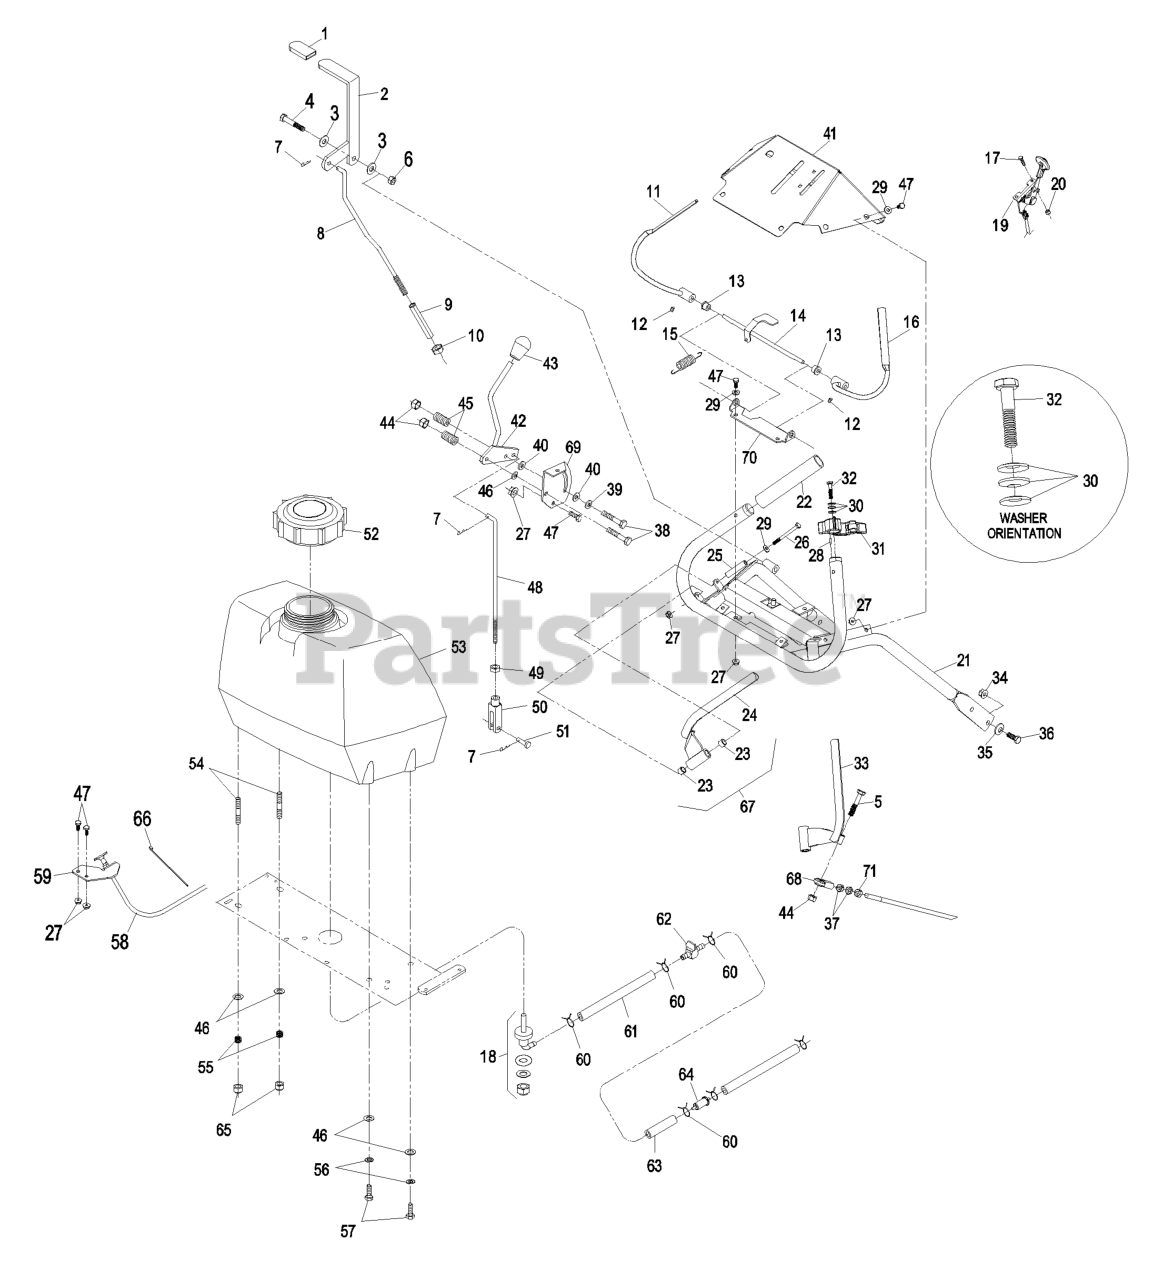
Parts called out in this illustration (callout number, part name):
1	GRIP-LEVER
3	WASHER-FLAT
4	SCREW-HH
5	SCREW-HH
6	NUT-LOCK, NI
7	PIN-COTTER
8	LINK,BLADE ENGAGE (PLTD)
9	TURNBUCKLE
10	NUT-HEX
12	SCREW-SET
13	BUSHING-NYLON
14	WLD,OPC LEVER AXLE
15	SPRING-EXTENSION
17	BOLT-CARR
18	FITTING-FUEL, BULKHEAD
19	CONTROL-THROTTLE
20	NUT-LOCK, NI
21	WLD,UPPER ECS HANDLE
22	GRIP-BAR, HANDLE
23	BUSHING-SLEEVE
25	BUSHING-LEVER, DRIVE
26	SCREW-HH
27	NUT-HF
29	WASHER-FLAT
30	WASHER-SPRING
31	ASM,LATCH RH THUMB
32	SCREW-HH
34	NUT-HHF, WHIZ
35	WASHER-BELLEVILLE
36	SCREW-HH
37	NUT-HJ
38	SCREW-HH
39	WASHER-FRICTION
40	WASHER-FRICTION
41	ASM,CONSOLE W/DECALS
43	KNOB, FE.LCKG. BLACK
44	NUT-LOCK, NI
45	SPRING-COMPRESSION
46	WASHER-PLAIN
47	SCREW-HH
48	ROD,SPEED CONTROL
49	NUT-JAM
50	YOKE-ADJUSTABLE
51	PIN-CLEVIS
52	CAP-FUEL, GAS
53	ASM,FUEL TANK W/B
54	STUD
55	SPRING-TANK, FUEL
56	WASHER-LOCK
57	SCREW-HH
58	CABLE-CHOKE
59	BRACKET-CABLE, CHOKE
61	HOSE-FUEL
62	VALVE-FUEL
63	HOSE-FUEL
64	Kawasaki Pn 41019-1055 Filter W/6" Fuel Line
65	NUT-LOCK, NI
66	TIE-CABLE
67	DRIVE LEVER-ASM, RH
68	JOINT-BALL, END
69	BRACKET,SHIFTER SLIDE (PL
70	BRACKET,OPC AXLE
71	NUT-HEX
